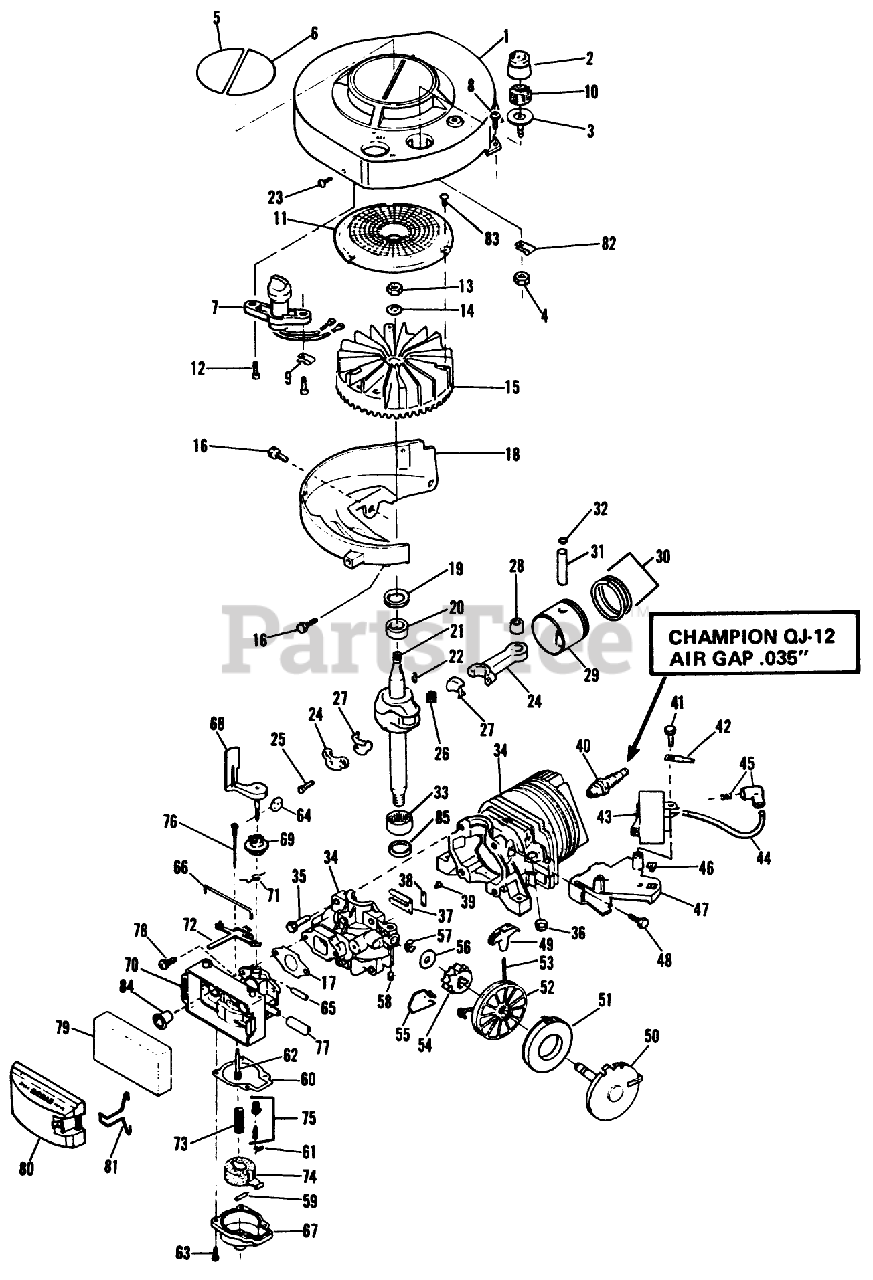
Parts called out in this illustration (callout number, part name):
4	LOCKNUT S
10	FILTER S
16	SCREW-SEMS
17	GASKET CARB S
20	BEARING V
23	SCREW F
25	SCREW-HSH
27	LINER ASM
28	BEARING AY F
32	RING-RETAINING
33	BEARING V
35	SCREW S
36	PLUG-CORE VF
38	PLATE-BACKUP, REED
42	TERMINAL S
44	HT LEAD&COVER XEV
46	NUT-CLIP
47	BRACKET S
49	HANDLE STARTER S
52	PULLEY STARTER S
55	SPRING F
56	WASHER S
63	SCREW-HH
64	DISC S
65	TUBING PRIMER S
66	RETAINER
68	AIR VANE&SHAFT S
69	COLLAR-ADJUST, AIRVANE
70	CARB BODY S
71	SPRING,THROTTLE S
72	LEVER S
73	FILTER-FUEL VS
76	NEEDLE ADJ. AY S
81	RETAINER-COVER, FILTER
83	SCREW F
85	SEAL-OIL
